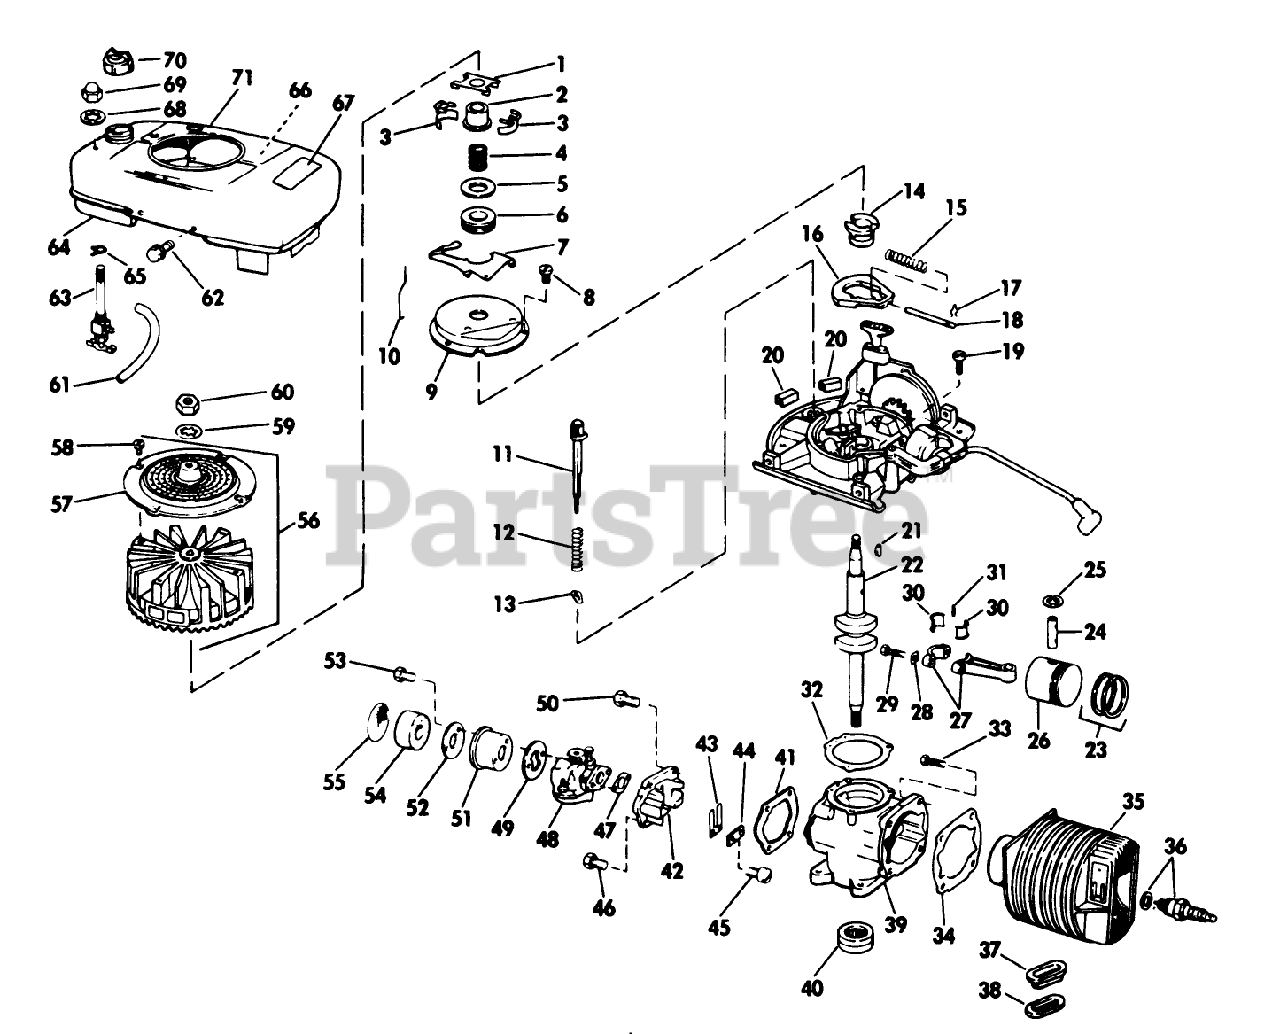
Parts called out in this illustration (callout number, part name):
2	COLLAR S
6	THRUST COLLAR S
7	LEVER-GOVERNOR S
8	SCREW S
9	DUST COVER S
12	SPRING S
14	SPARK ADV. S
15	SPARK ADV. SPRING S
16	FLYWEIGHT S
17	SPARK ADJ. SPRING
18	PIN,SPARK ADV. S
19	SCREW S
25	RING-RETAINING
30	Liners-Connecting Rod
32	GASKET S
34	GASKET S
36	Spark Plug and Gasket
38	GASKET S
42	Reed Plate Assembly
44	PLATE-BACKUP, REED
46	SCREW S
47	Gasket-Carburetor
48	Carburetor Assembly
49	GASKET S
50	SCREW S
52	BACK-UP PLATE
54	ELEMENT
56	Flywheel Screen Assy.
62	SCREW S
63	VALVE&SCREEN SM
65	CLAMP - HOSE S
69	PALNUT S
